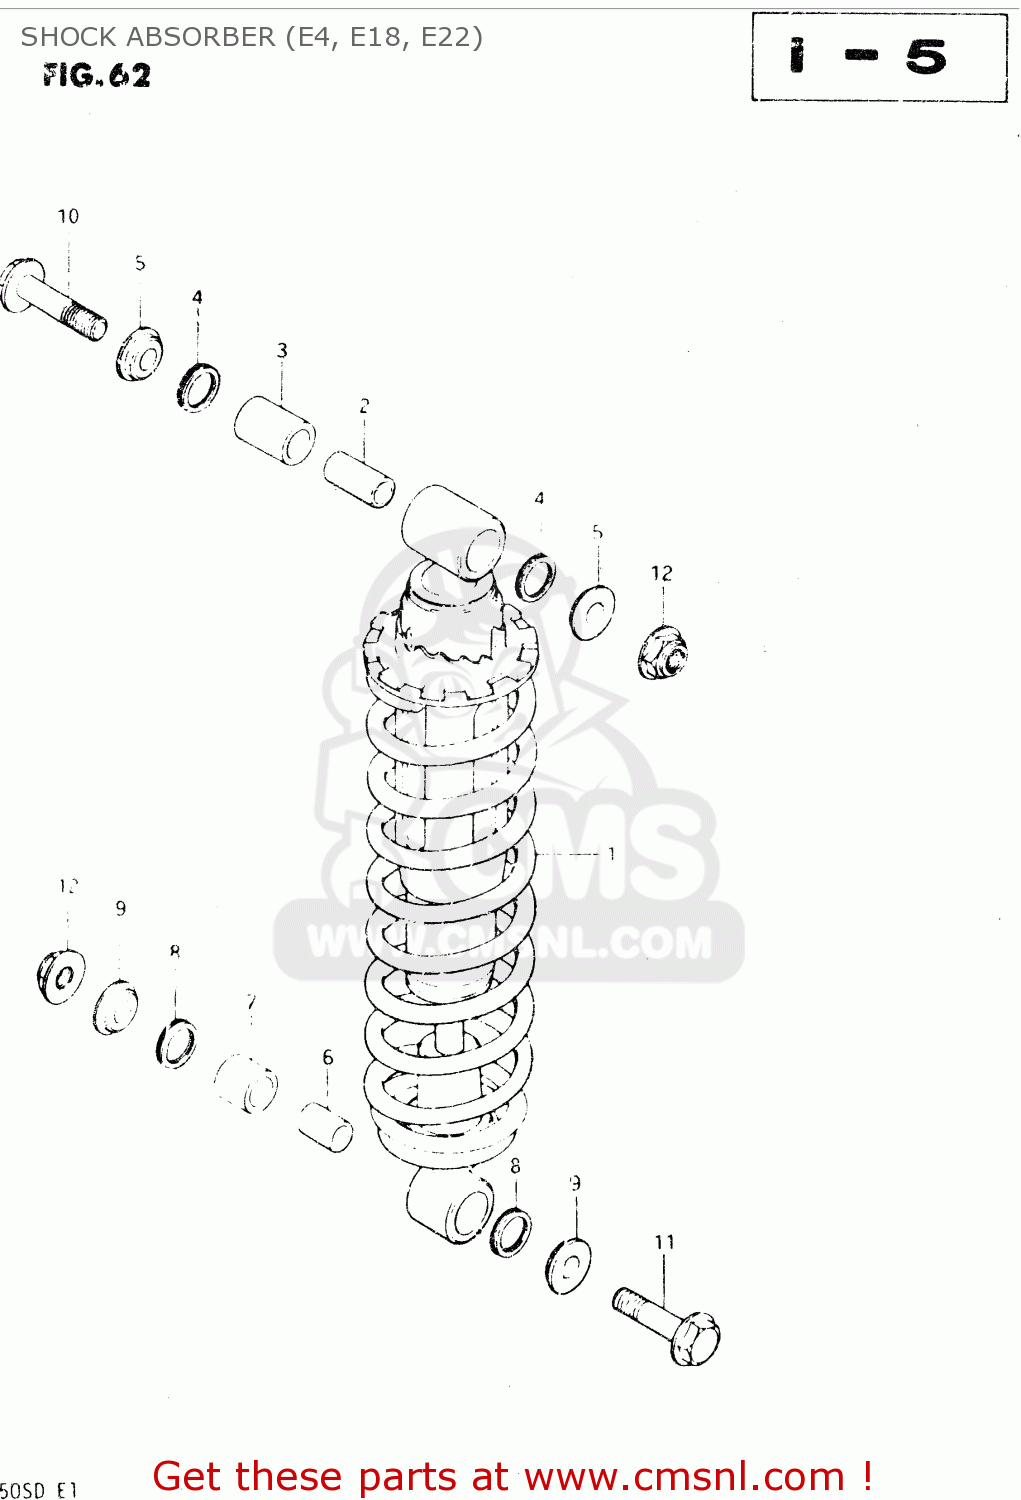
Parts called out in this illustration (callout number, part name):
1	SHOCK ABSORBER, REAR
2	BUSH
3	BUSHING,REAR SHOCK,UPPER
4	O-RING,FORK INNER TUBE
5	COLLAR
6	BUSHING,REAR SHOCK ABSORBER
7	BUSHING,REAR SHOCK,LOWER
8	O-RING,FORK INNER TUBE
9	COLLAR
10	BOLT(10X60)
11	BOLT(10X50)
12	NUT
